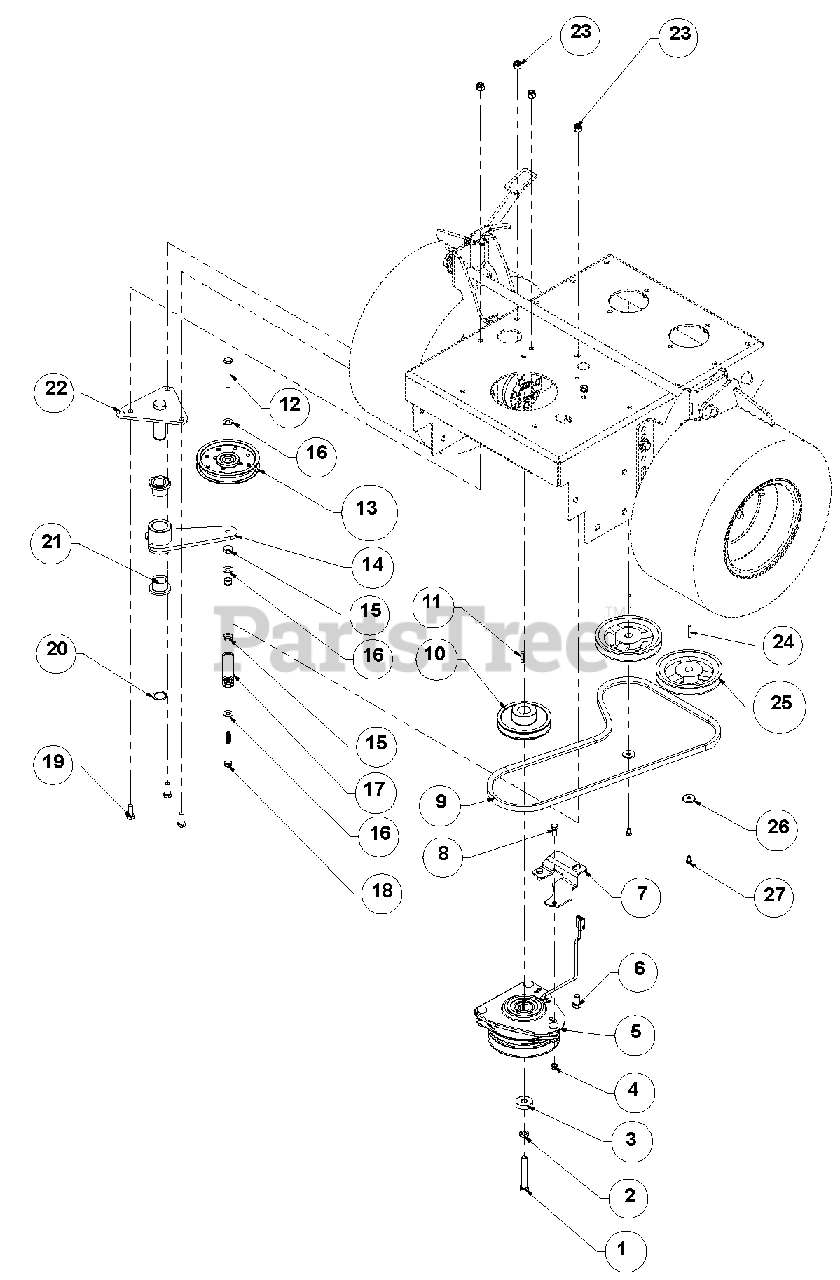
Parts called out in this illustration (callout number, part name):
1	Bolt, .4375-20 x 3.00 Hex 5
2	Washer, .438 Medium Spring Lock
3	Spacer, .468 x 1.38 x .375
4	Locknut, .3125-18 Nyloc
5	Clutch Assembly, OGURA
6	Bolt, .4375-14 x .750 Hex 5
7	Plate, Clutch Dog
8	Bolt, .3125-18 x .750 Hex 5
9	Belt, HA 55.1 Elbow AMD OHR
10	Pulley, V-Belt 4.45 x 1.00 with Key
11	Key, .250 x .250 x .995 TPR
12	Bolt, .38-16 x 2.50 Hex 5
13	Pulley, Flat 4.50 x .375 W/BRG
14	Weldment, Idler Arm
15	Locknut, .38-16 Whiz
16	Washer, .406 x .813 x .065 Flat
17	Spring, External .900 x .135 x 4.50
18	Bolt, .38-16 x 3.00 Hex 8
19	Bolt, .38-16 x 1.00 Hex 5
20	Snap Ring, 1.00 x .042 External
21	Bearing, Flange 1.00 x 1.25 x 1.00
22	Weldment, Idler Pivot Mount
23	Locknut, .38-16 Nyloc
24	Key, M5 x M5 x M30 RD
25	Assembly, Pump Pulley w/Set Screw
26	Washer, .250 Wide Heavy Flat
27	Bolt, M6 x 1.00 x 10 Hex 8.8
